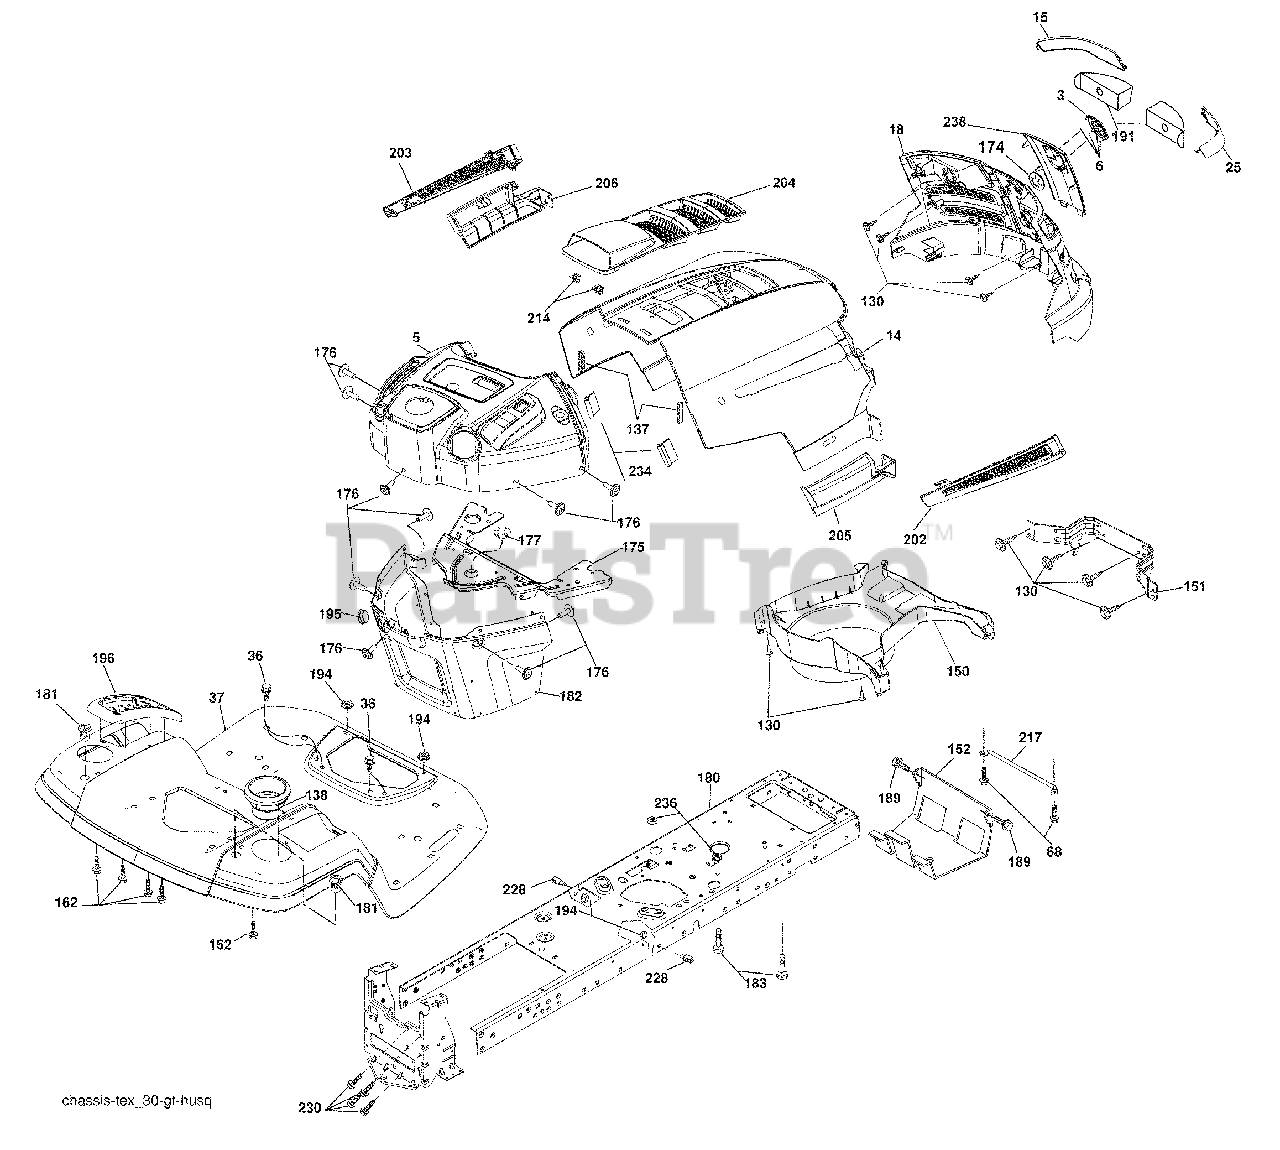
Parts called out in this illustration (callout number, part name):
3	Logo
5	Dash
14	Hood
15	Lens LH
18	Grille/Lens Asm.
25	Lens RH
36	Screw 5/16-18 x 3/4
37	Fender
68	Screw THDROL 5/16-18 x 1/2
130	Screw 10 x 3/4 Single Lead-Hex
138	Cupholder
151	Bracket Pivot
152	Shield Browning
175	Crossmember
176	Screw 10-24 x 5/8
177	Bushing Steering
180	Chassis
181	Bushing Mtg. Fender Crgo
182	Dash Lower
183	Bolt 5/16-18 UNC x 1-1/4
189	Screw 5/16-18 x 3/4
191	Insert Reflective
194	Nut Lock Hex Flange 5/16-18
195	Plug Dash
196	Console Asm. Deck Lift
202	Vent Side Hood RH
203	Vent Side Hood LH
204	Vent Top Hood
205	Skirt Side RH
206	Skirt Side LH
214	Clip Retainer
217	Rod Pivot Hood
228	Stud Fastener
230	Bolt Shoulder 5/16-18
234	Bumper Hood
236	Nut Lock 5/16-18 UNC
238	Trim
239	Clip Tinnerman
